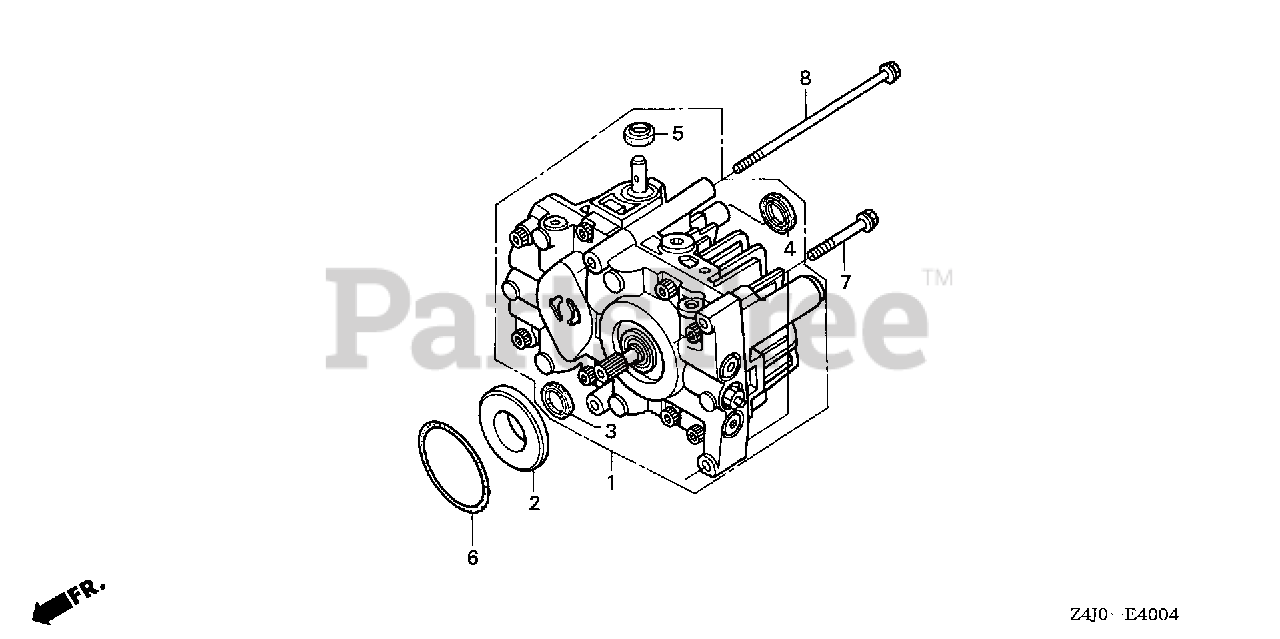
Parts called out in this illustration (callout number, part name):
1	H.S.T. ASSY.
2	BOSS, GUIDE
4	OIL SEAL (15X35X7)
6	O-RING (64X2) (NOT AVAILABLE)
7	BOLT, FLANGE (8X45)
8	BOLT, FLANGE (8X115)
